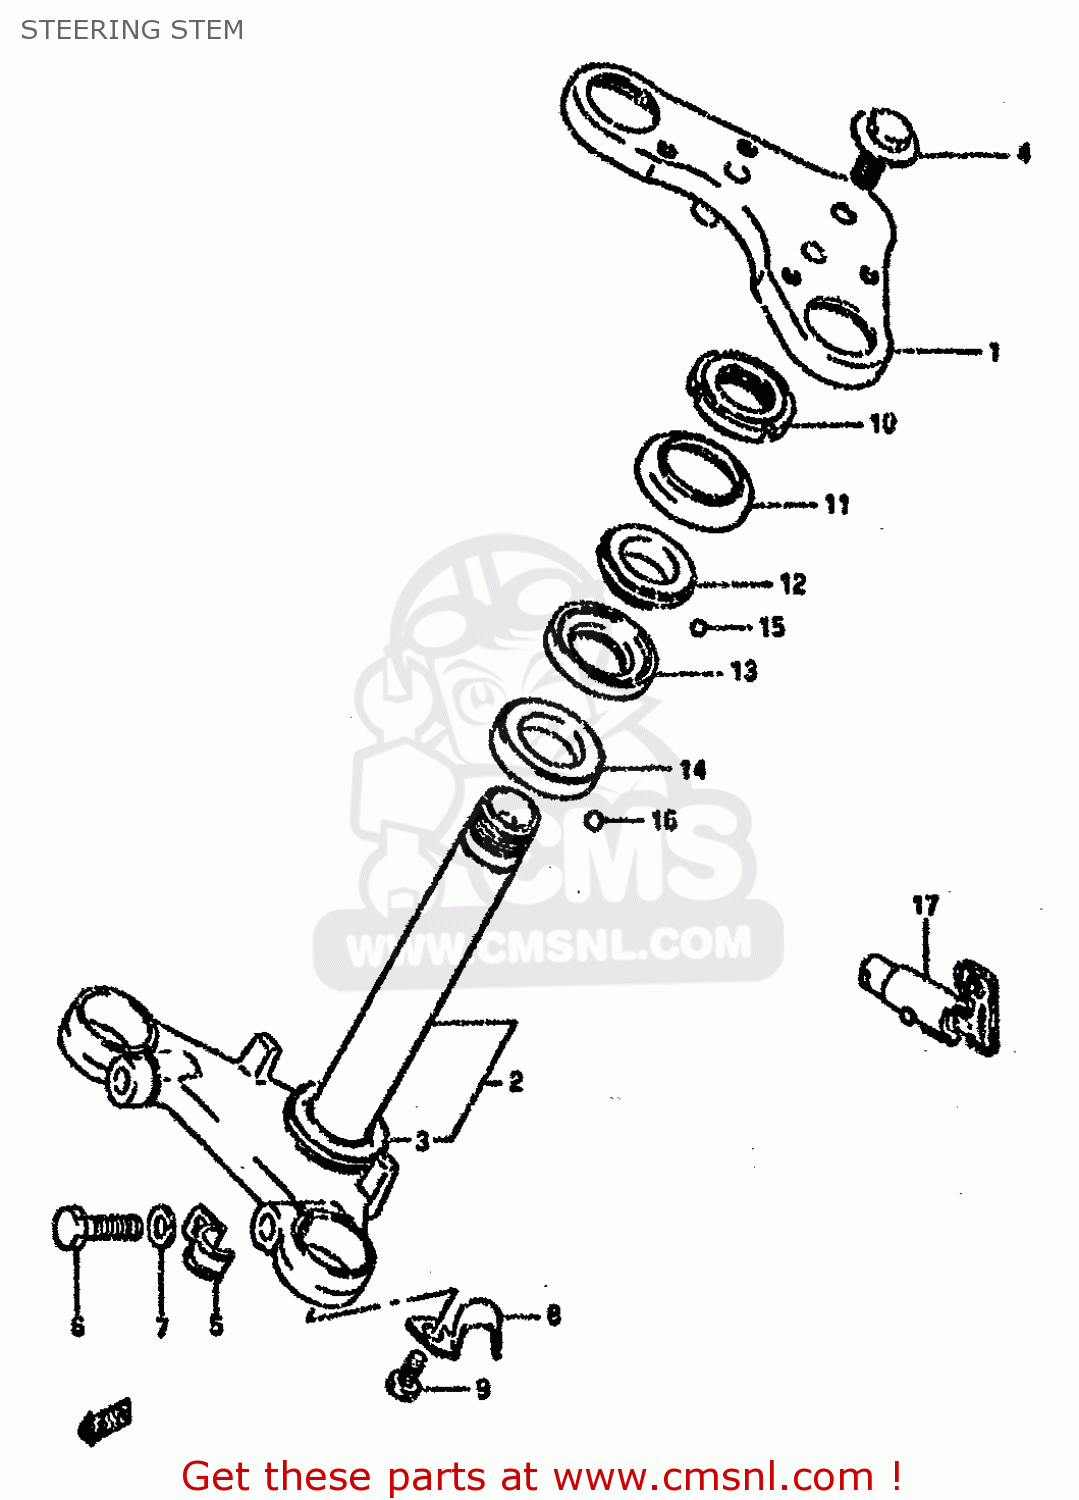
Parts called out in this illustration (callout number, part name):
1	STEM HEAD, STEERING (BLACK)
2	STEM, STEERING (BLACK)
3	RACE,STEERING OUTER LWR
4	BOLT
5	CLIP,SPEEDOMETER CABLE
6	BOLT 10X30
7	WASHER,LOCK
8	CLIP
9	BOLT
10	NUT,STEERING STEM(25X44X10)
11	DUST SEAL,STEERING UPR
12	RACE,STEERING OUTER UPR
13	RACE,STEERING INNER UPR
14	LACE,STEERING INNER LWR
15	BALL
16	BALL
17	LOCK ASSEMBLY,STEERING (NEI
